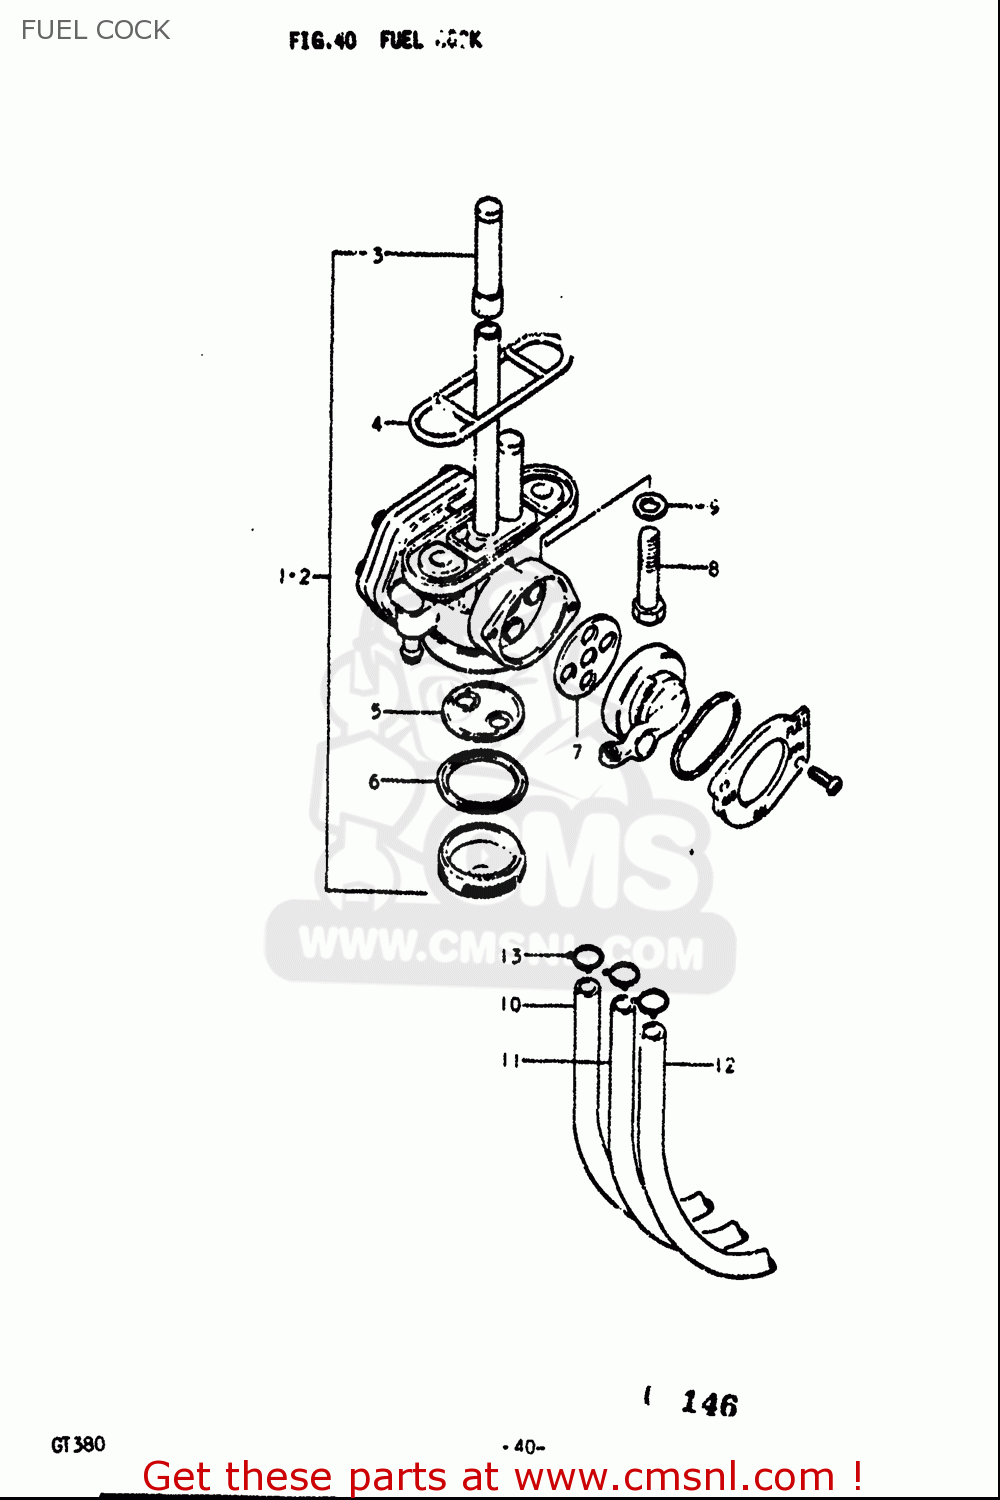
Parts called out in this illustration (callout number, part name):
1	COCK ASSY,FUEL
2	COCK ASSY,FUEL
3	FILTER
4	GASKET, FUEL COCK (NAS)
5	FILTER,CUP
6	GASKET,CUP (NAS)
7	GASKET (NAS)
8	BOLT
9	GASKET(5.8X13X1.2) (NAS)
10	HOSE(5X8.2X2000)
11	HOSE(5X9X600)
12	HOSE(5X8.2X600)
13	CLIP
